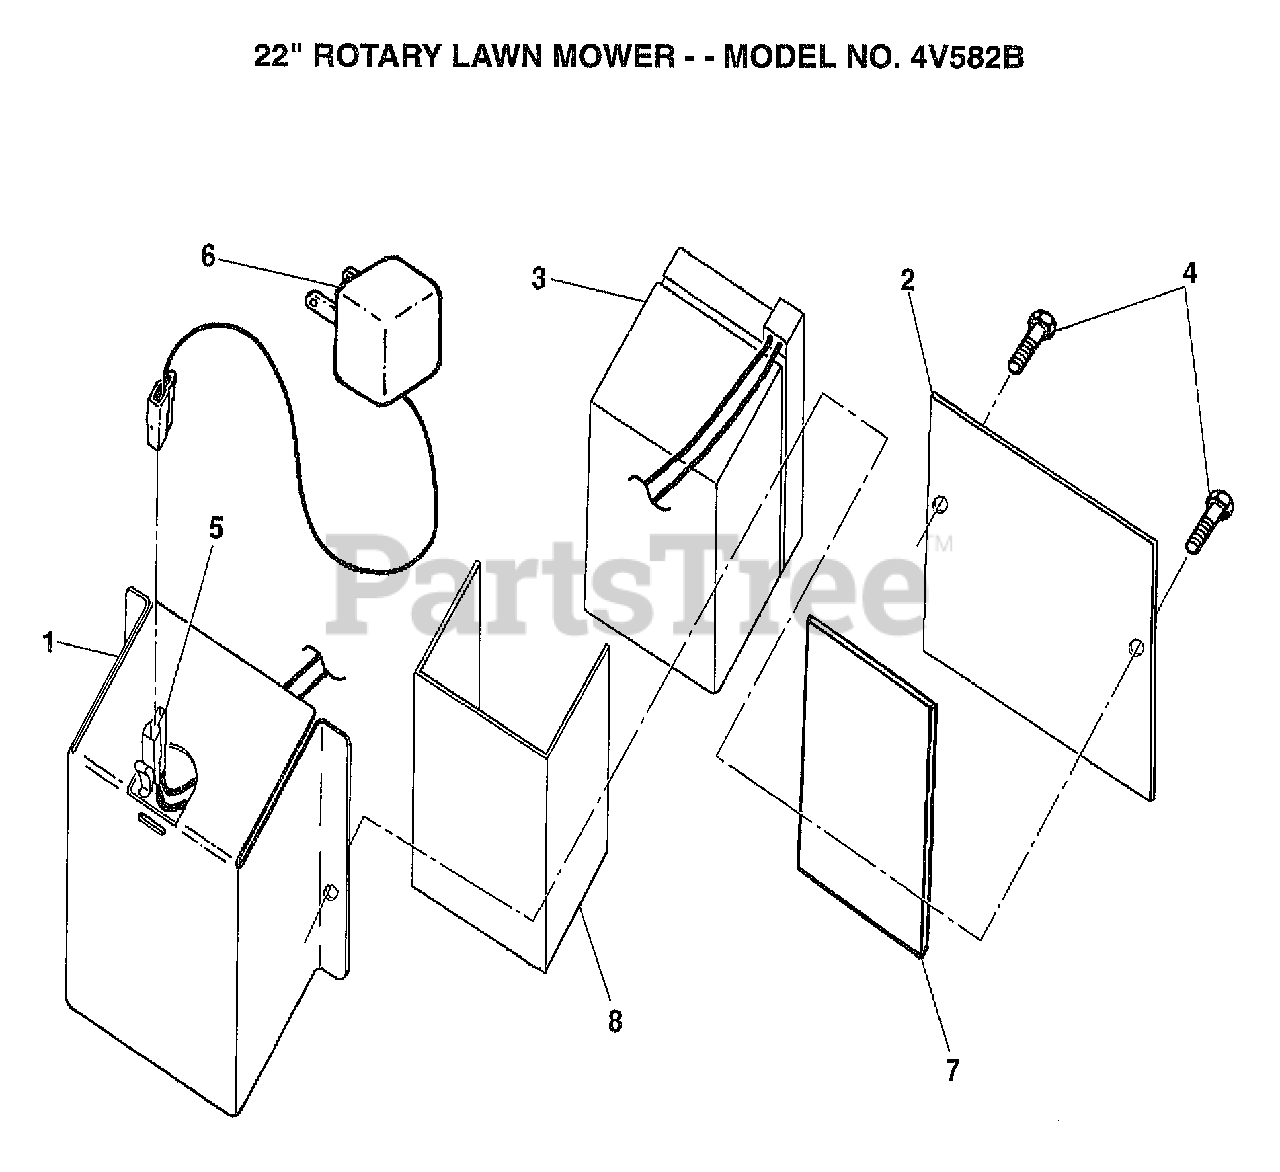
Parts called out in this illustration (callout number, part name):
4	TAPPING SCREW
5	CONNECTOR PM
6	CHARGER PM
7	"PAD PM, BATTERY"
8	"WRAP, BATTERY"
